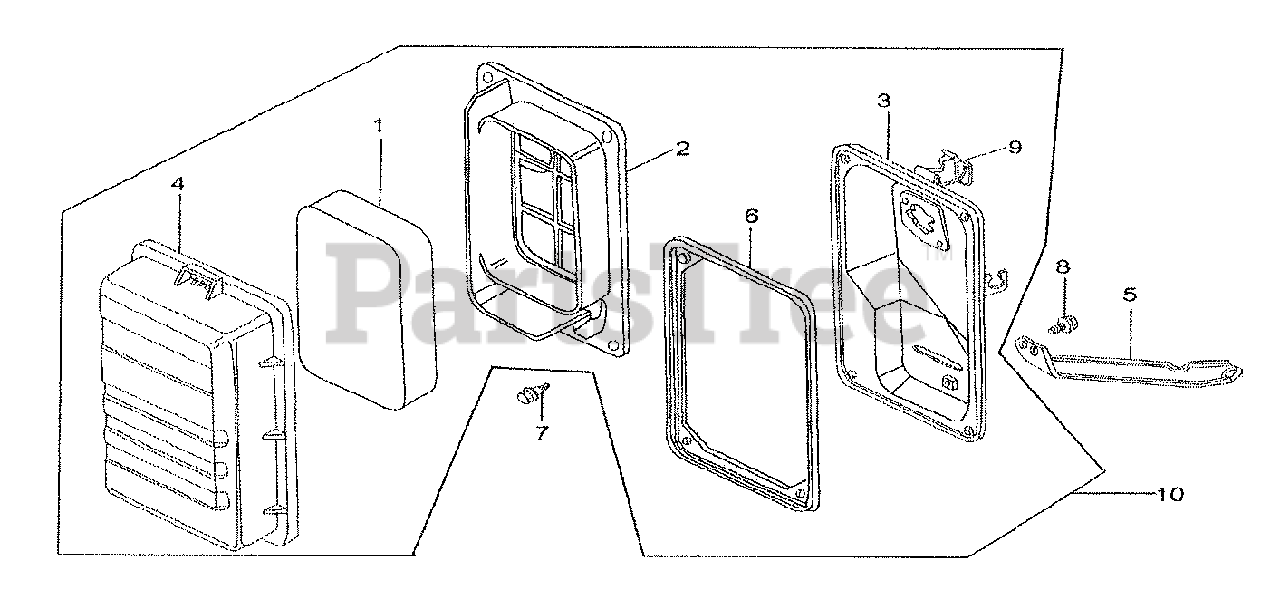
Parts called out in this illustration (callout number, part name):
1	ELEMENT, AIR/C
2	STAY, ELEMENT
3	CASE COMP, AIR/C
4	COVER, AIR/C
5	STAY, AIR/C
6	SEAL, AIR/C
7	BOLT, WINKER,SET 5 X 25
8	BOLT, FLANGE, 6 X 12
